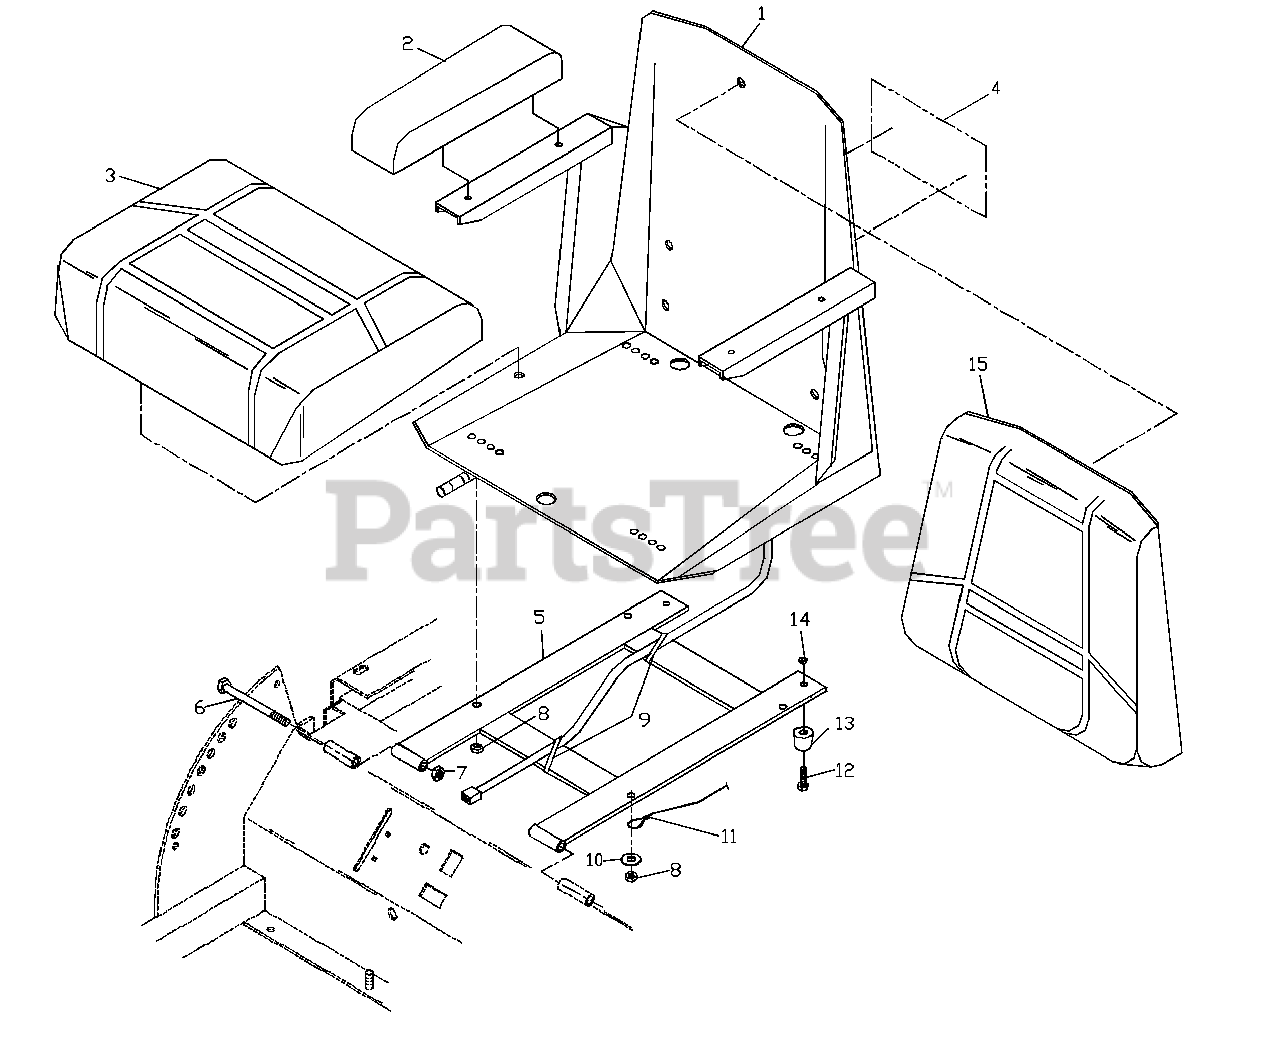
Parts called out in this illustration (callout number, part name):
1	COMPLETE-SEAT
2	ARM REST CUSHION
3	SEAT CUSHION W/SWITCH
4	DECAL, CROWN
5	SEAT MOUNT
6	HCS 3/8C X 4 1/2
7	NUT 3/8C CENTERLOCK
8	NUT 5/16C CENTERLOCK
9	PLASTIC TIE
10	5/16 FLAT WASHER
11	SEAT LANYARD
12	#10-24 X 1/2 SLOTTED SCREW
13	SEAT BUMPER
14	#10-24 NYLOC NUT
15	SEAT BACK CUSHION
